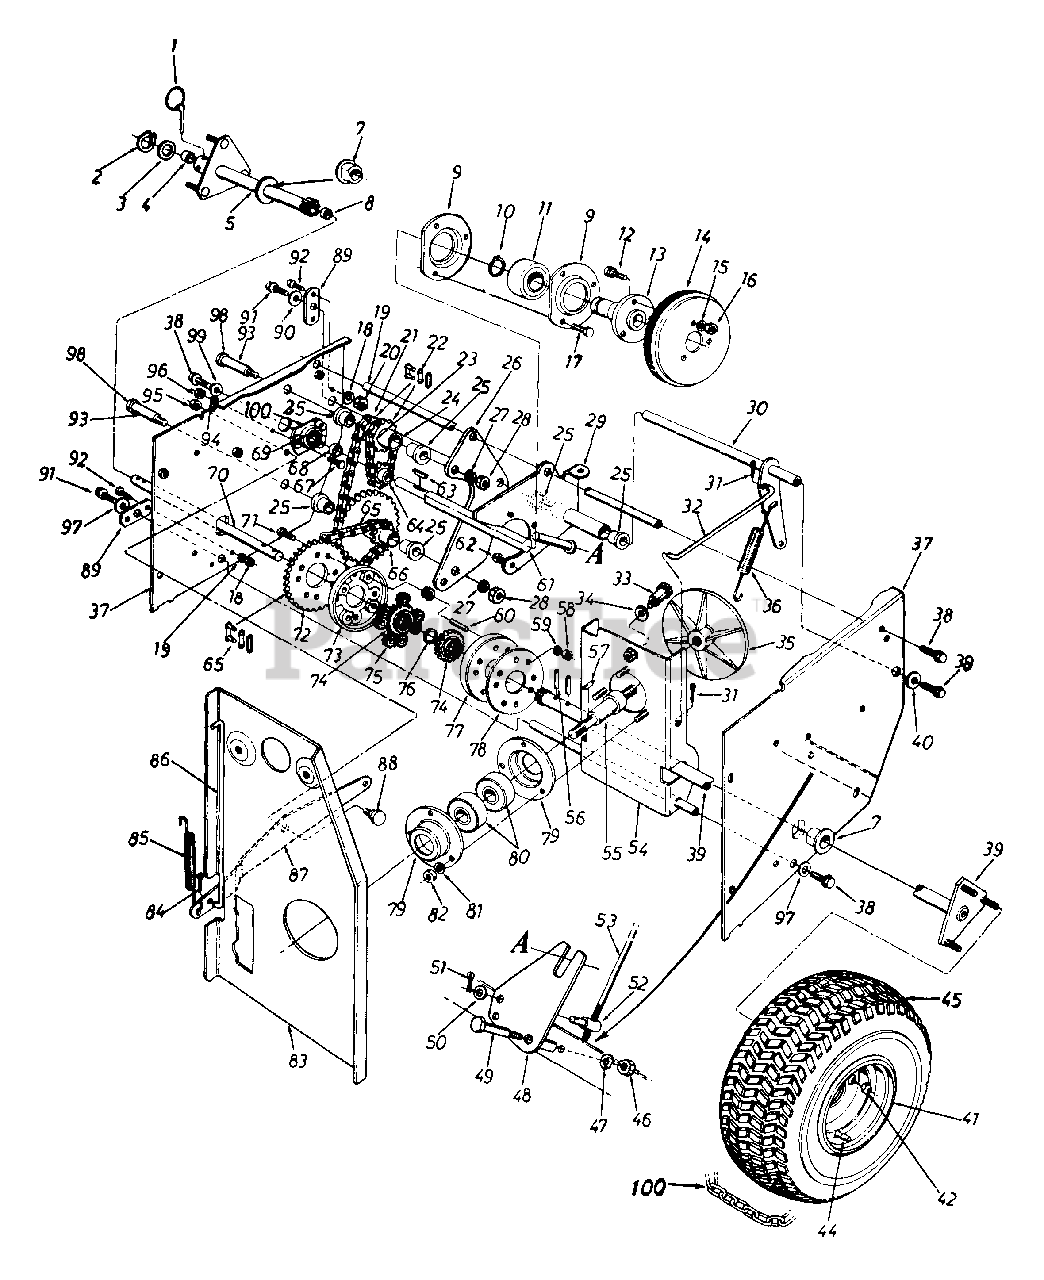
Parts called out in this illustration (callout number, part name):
1	Klick Pin 1/4" Dia x 1.75"
2	Snap Ring .625" Shaft
3	Fl-Wash..62" I.D. x 1.25"
4	Sleeve Brg.
5	Differential Tubing Ass'y.- R.H.
7	Flange Brg. w/Flats 1" I.D.
8	Sleeve Brg.
9	Bearing Housing
10	Snap Ring - 1.00" Dia.
11	Ball Brg..25MM x 52MM x 15MM Thk.
12	Hex Sems Bolt 5/16-18 x .75" Lg.
13	Friction Wheel Adapter
14	Friction Wheel Ass'y.
15	L-Wash. 5/16" I.D.
16	Hex Nut 5/16-18 Thd.
17	Hex Bolt 1/4-28 x .62" Lg.
18	L-Wash. 1/4" I.D.
19	Sliding Support Axle
20	Hex Nut 1/4-20 Thd.
21	#41 Chain - 1/2" Pitch x 43 Links
22	Master Link
23	#41 Chain - 1/2" Pitch x 19 Links
24	9 and 14 Teeth Sprocket Hub Ass'y.
25	Flange Brg..630" I.D.
26	Chain Support Brkt.
27	L-Wash. 3/8" I D.- H.D.
28	Hex L-Jam Nut 3/8-24 Thd.
29	Sliding Brkt. Ass'y.
30	Drive Clutch Brkt, Ass'y.
31	Inter. Cot. Pin 5/16" Dia.
32	Drive Clutch Rod 7.38" Lg.
33	Shld. Bolt
34	Bell-Wash..44" I.D. x .88"
35	Aluminum Drive Plate
36	Extension Spring 4.31" Lg.
37	Frame Ass'y.
38	Hex L-Bolt 5/16-18 x .62"
39	Differential Shaft Ass'y.
40	Fl-Wash..345" I.D. x.75"
41	Rim Only - 16"
42	Cone Nut 3/8-24 Thd.
44	Tubeless Air Valve
45	Wheel Ass'y. Comp. 16 x 6.5
46	Hex Jam Nut 3/8-16 Thd.
47	L-Wash. 3/8" I.D.
50	Fl-Wash..344" I.D. x .62"
51	Cotter Pin 3/32" Dia. x 75"
52	Adjustment Ferrule
53	Shifting Rod
56	H-Spring Pin Spiral 3/16" Dia x 1.25" Lg.
57	#61 Hi-Pro Key 3/32 x 5/8 Dia.
58	Hex Nut 1/4-28 Thd.
59	L-Wash. 1/4" I.D.
60	Differential Pin
61	Hex Shaft
62	Hex L-Nut 1/4-28 Thd.
63	#9 Hi-Pro Key 3/32 x 5/8" Dia.
64	8 Teeth Sprocket
65	#420 Chain - 50 Pitch x 37 Links
66	9 and 32 Teeth Sprocket Hub Ass'y
67	Hex Bolt 1/4-20 x .62" Lg.
68	Spacer .51" I.D. x .69" O.D.
69	Ball Bearing
70	Differential Connecting Shaft
71	Hex Bolt 1/4-28 x .1.75" Lg.
72	28 Teeth Sprocket
73	Differential Housing
74	20 Tooth Spur Gear
75	9 Tooth Spur Gear
76	Fl-Wash..62" I.D. x 1.25"
77	Differential Housing
78	Differential Hsg. Support Plate
79	Bearing Housing
80	Ball Brg 787" I.D. x 1.85"
81	L-Wash. 5/16" I.D.
82	Hex Nut 5/16" Thd.
83	Engine Brkt Ass'y
84	Inter. Cotter Pin 5/16" Dia.
85	Extension Spring 3.18" Lg.
86	Auger Clutch Rod 31" Dia. x 10.62" Lg.
87	Auger Clutch Brkt
88	Shld. Bolt .625 Dia. x .170"
89	Pivot Axle Brkt
90	Fl-Wash..345" I.D. x .75"
91	Hex L-Bolt 5/16-18 x .62"
92	Hex Bolt 1/4-20 x .62" Lg.
93	Sprocket Hub Tubing 1.88"
94	L-Wash..345" I.D.
95	Hex Cent. L-Nut 3/8-16 Thd.
96	Hex Nut 1/4-20 Thd.
97	Fl-Wash..344" I.D. x .875"
98	Hex Bolt 3/8-24 x 2.75" Lg
99	Bell-Wash..345" I.D. x .88"
100	Tire Chain
